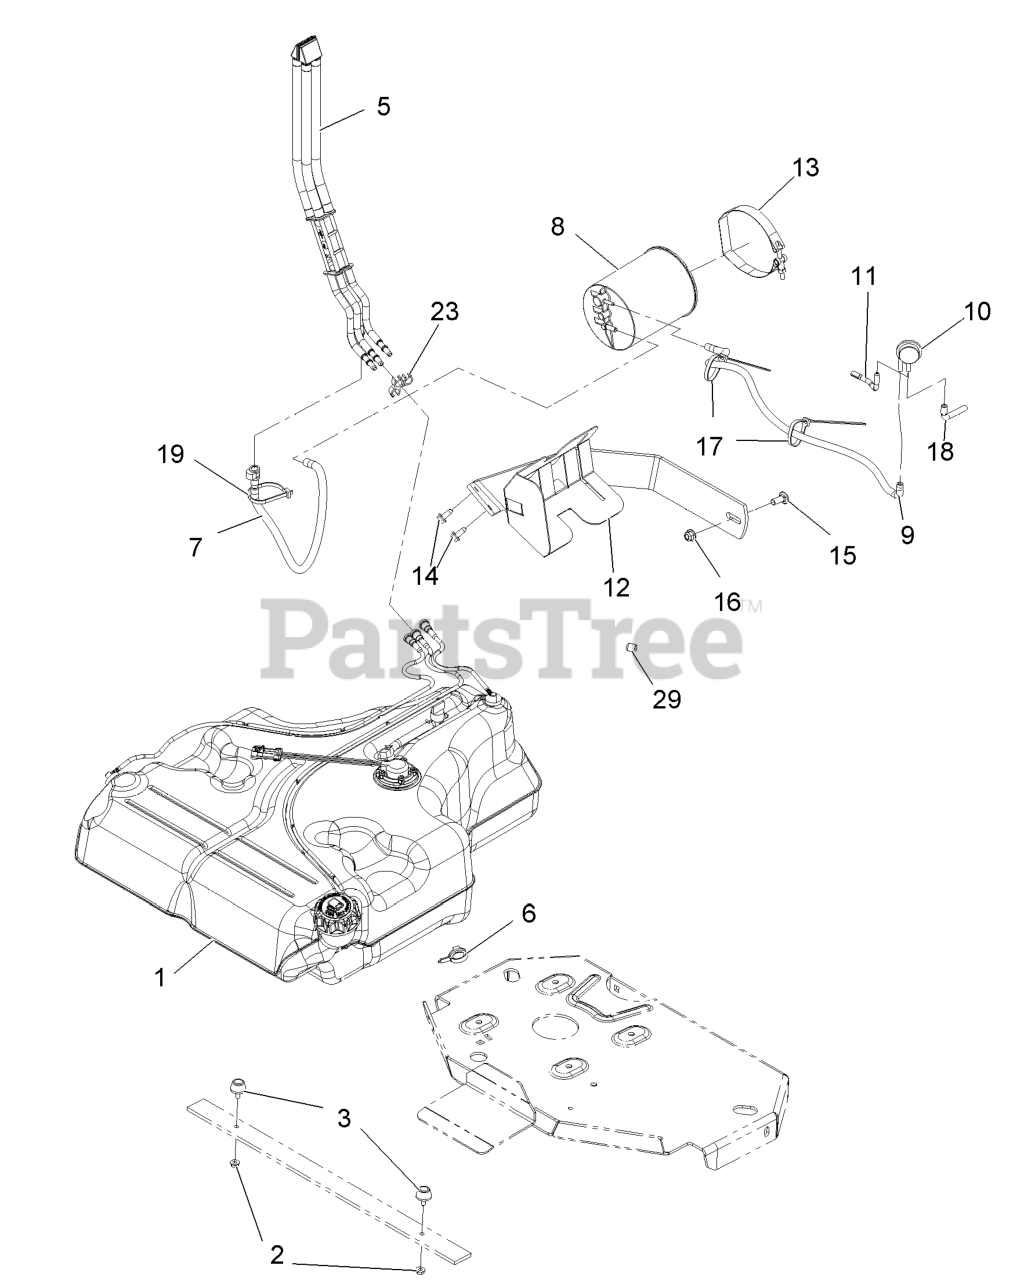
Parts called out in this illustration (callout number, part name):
3	BUMPER-RUBBER
5	FUEL MANIFOLD VENT ASM
6	CLAMP-HOSE
7	VENT HOSE ASM
8	CANISTER-CARBON, 1200CC
9	HOSE-VENT, FORMED
10	VALVE-CONTROL, VACUUM
11	HOSE-VENT, FORMED
12	MOUNT-CANISTER
13	CLAMP, T-BOLT
14	Screw-HWH 5/16-18 X 3/4 Tf
15	SCREW-CARR
16	NUT-HF, NI
17	TIE-PLASTIC
18	HOSE-VENT, FORMED
19	TIE-PLASTIC
23	CLIP-SPACER
29	PLUG-PORT
